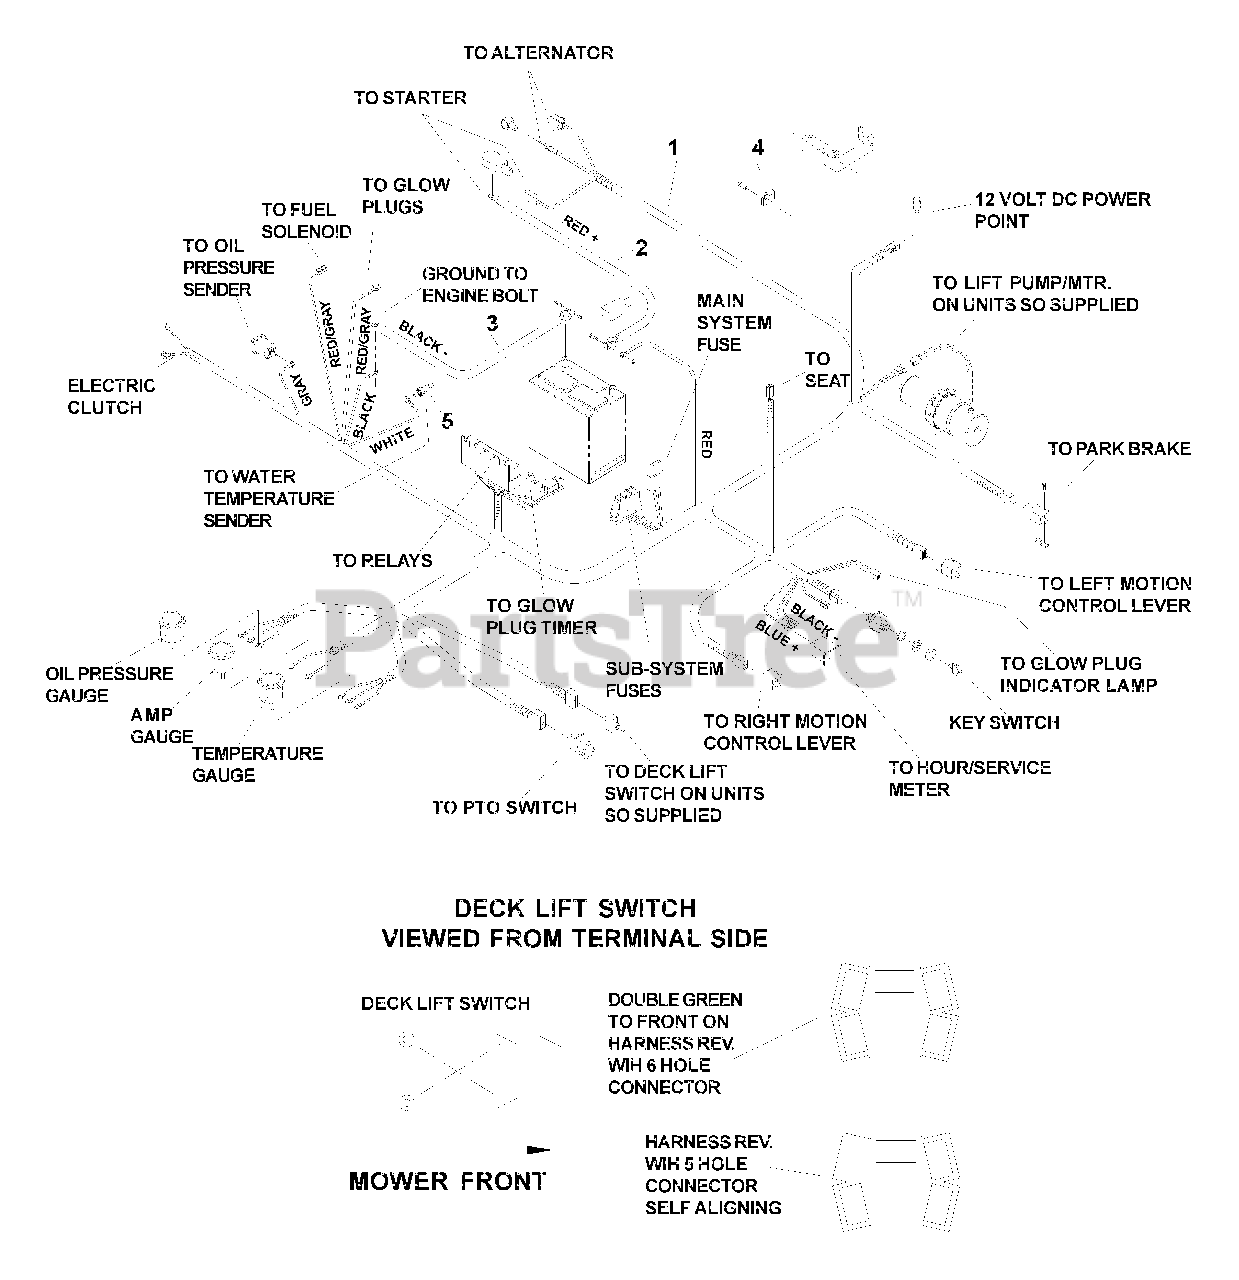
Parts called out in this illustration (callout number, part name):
1	Harness, engine, diesel
2	Cable, postive
3	Cable, negative
5	Sender, temperature
